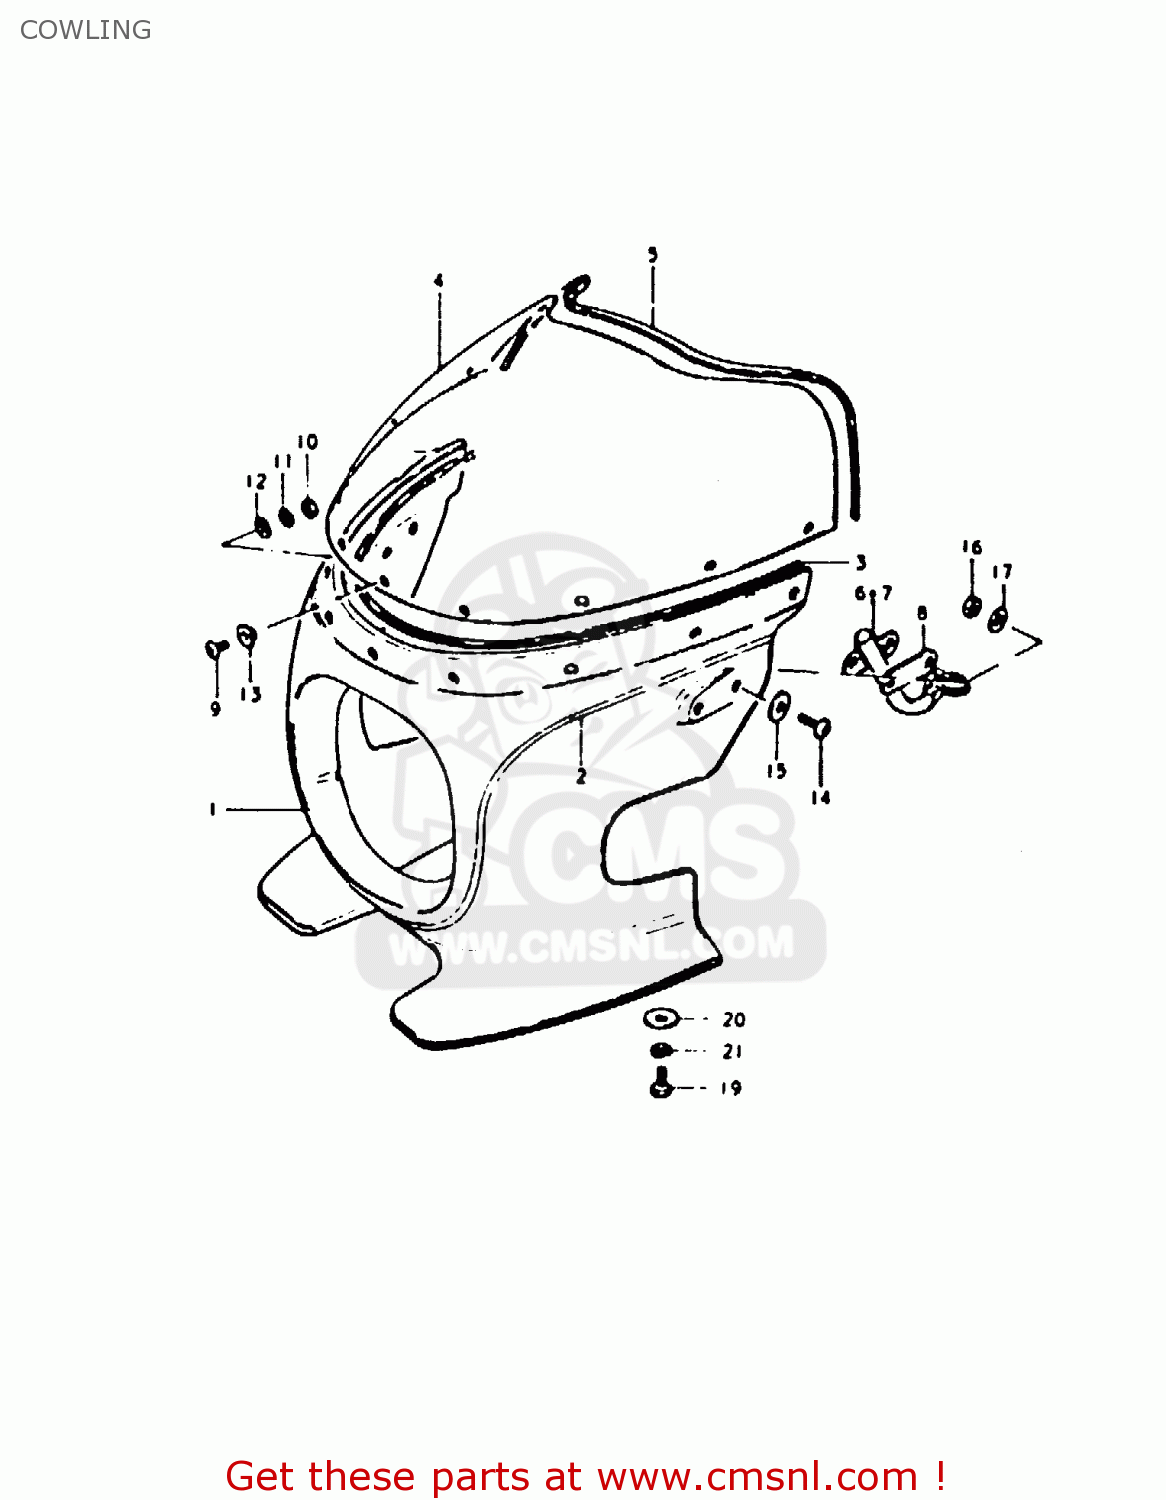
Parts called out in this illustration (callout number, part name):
1	BODY ASSEMBLY,COWLING
2	TAPE SET
3	MOLDING,COWLING
4	WINDOW,COWLING
5	MOLDING,COWLING
6	BRACE,COWLING
7	BRACKET,COWLING,UPPER
8	CUSHION,COWLING
9	SCREW M5X12 DIN 7985/N
10	NUT
11	LOCK WASHER
12	WASHER
13	CUSHION
14	SCREW
15	WASHER(6.5X16X1.2)
16	NUT
17	WASHER
18	LOCK WASHER
19	BOLT, UPPER
20	WASHER
21	LOCK WASHER
